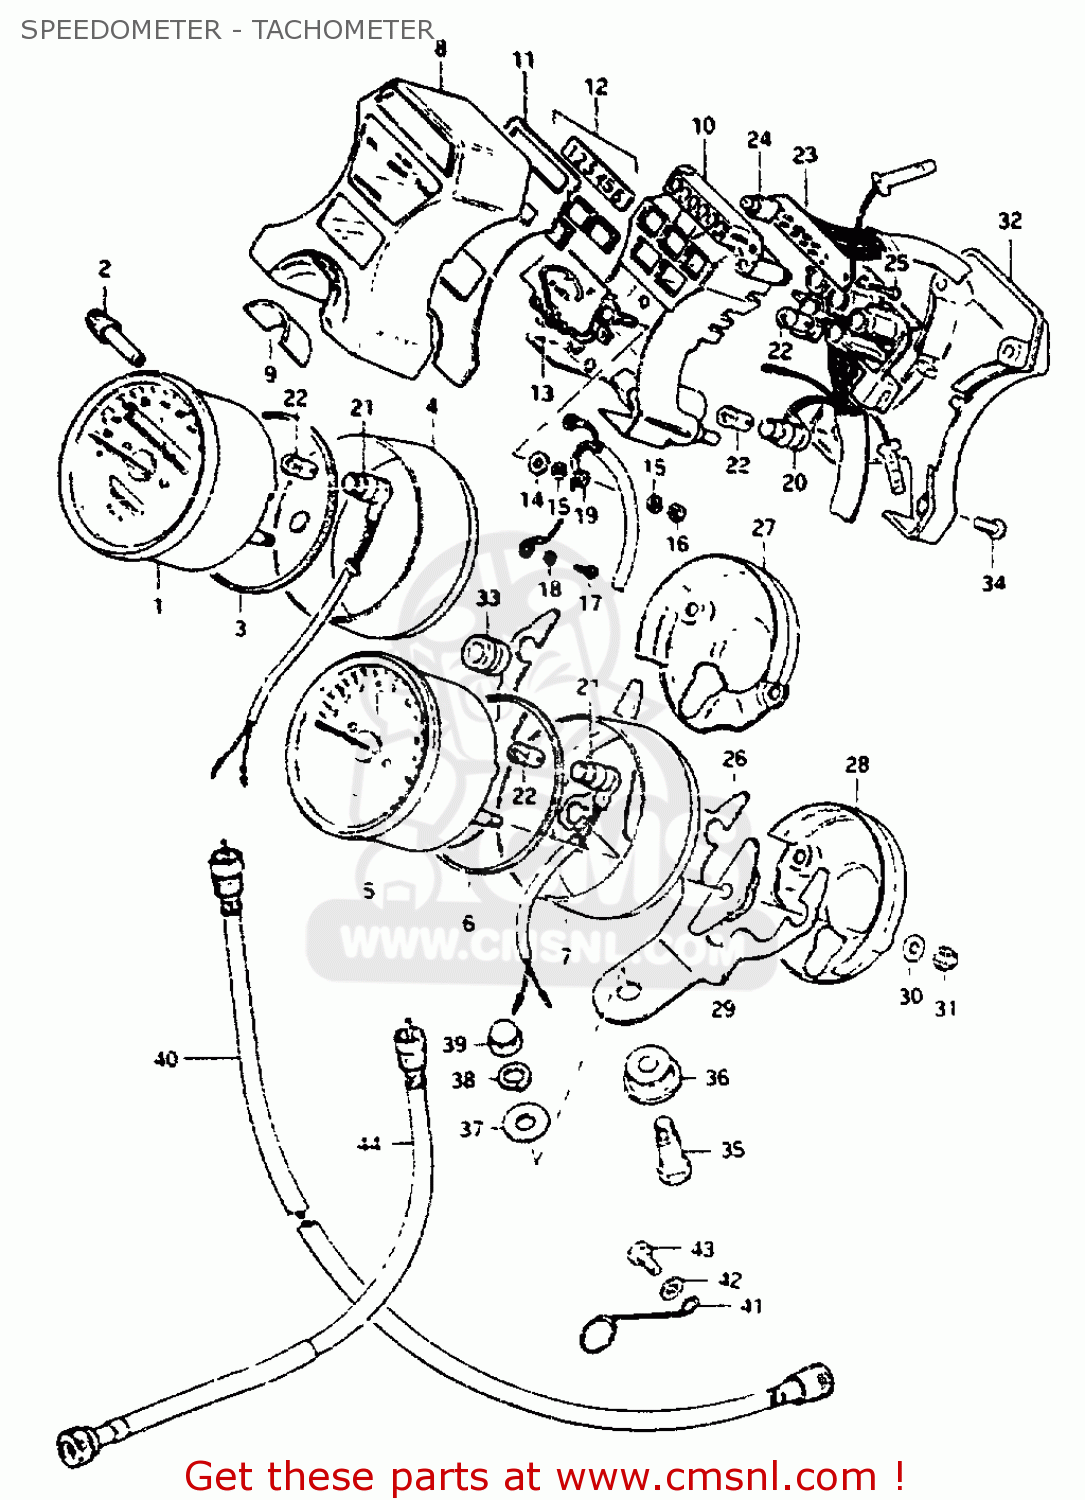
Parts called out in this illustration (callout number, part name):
1	SPEEDOMETER
2	KNOB
3	CUSHION
4	COVER,SPEEDOMETER
5	TACH0METER
6	CUSHION
7	COVER,TACHOMETER
8	CASE,PILOT BOX,OUTER
9	SEAL,IGNITION SWITCH
10	CASE, PILOT BOX INNER
11	PLATE,PILOT BOX
12	LENS SET,PILOT
13	METER,FUEL
14	WASHER
15	LOCK WASHER
16	NUT
17	SCREW
18	LOCK WASHER
19	LEAD WIRE, FUELMETER
20	SOCKET
21	SOCKET,METER
22	BULB(12V3.4W,STANLEY,A72A)
23	INDICATOR ASSEMBLY,GEAR POSITION
24	BULB(14V1.12W)
25	SCREW
26	BRACKET,COMBINATION METER
27	ORNAMENT,SPEEDOMETER
28	COVER,TACHOMETER
29	CUSHION,METER
30	WASHER
31	NUT
32	COVER,PILOT BOX,UNDER
33	CUSHION,PILOT BOX
34	SCREW,PILOT BOX
35	BOLT
36	CUSHION,METER
37	WASHER(8.5X23X1.2)
38	LOCK WASHER
39	NUT,M8X1.25X12
40	CABLE ASSEMBLY,SPEEDOMETER
41	GUIDE,SPEEDOMETER CABLE
42	BOLT, UPPER
43	WASHER
44	CABLE ASSEMBLY,TACHOMETER
